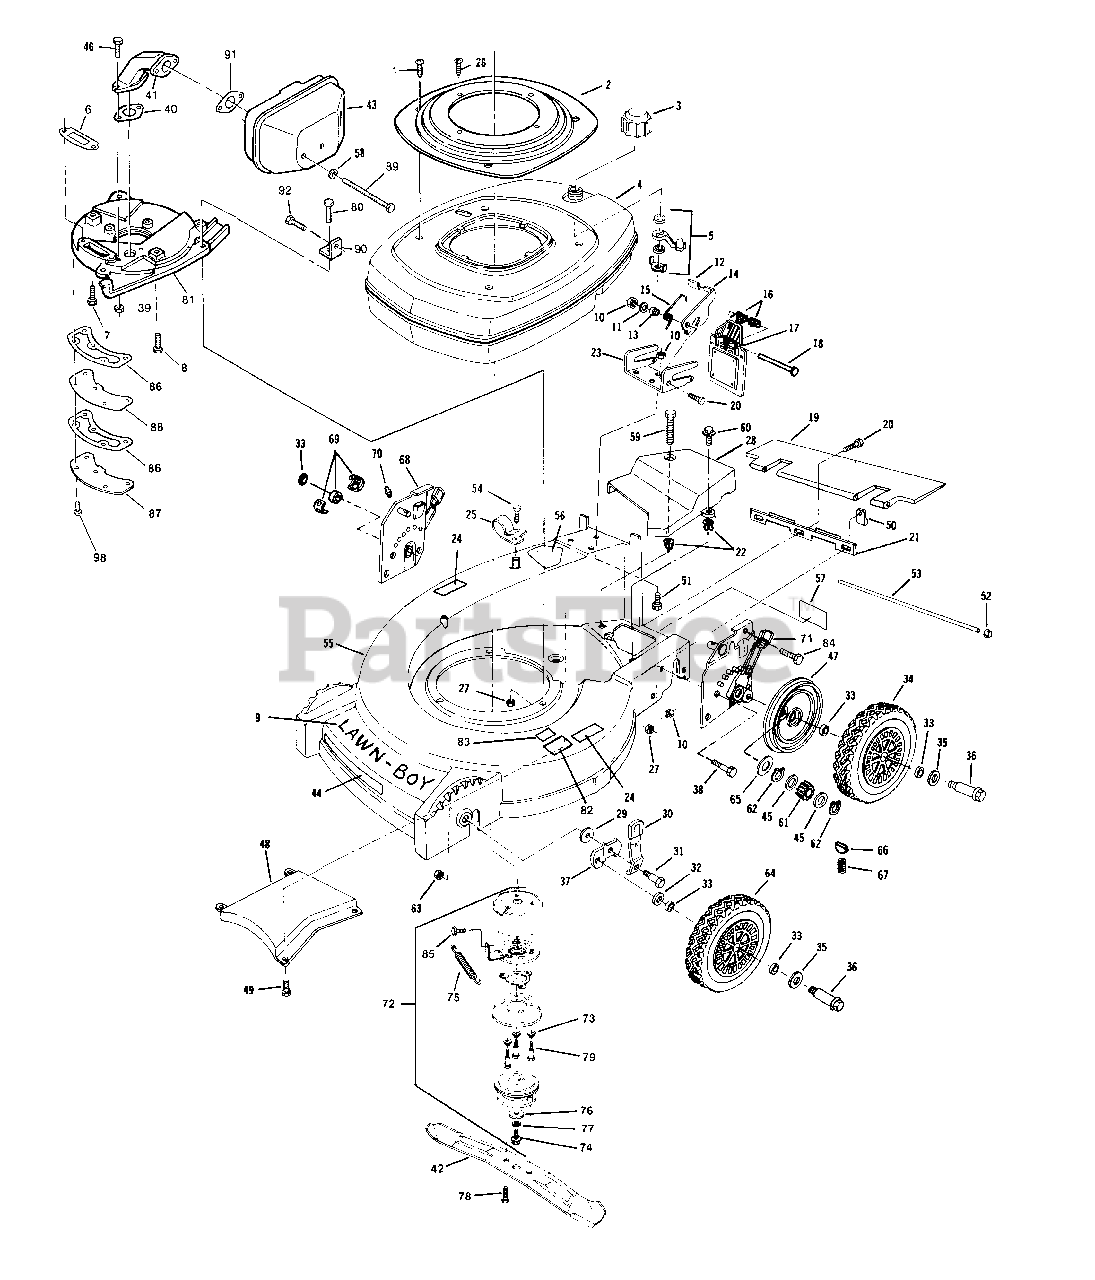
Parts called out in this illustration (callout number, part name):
1	Screw
2	Starter Base and Nut Assembly
3	Fuel Cap
4	Shroud Tank and Valve Assembly
5	Fuel Shut-Off Assembly
6	Gasket-Exhaust
7	Screw-Muffler to Block
8	Screw-Muffler Plate to Block
9	Decal-Lawn-Boy
10	Nut-Latch Brk't. and Trl. Shield
11	Washer
12	Knob-Latch
13	Stepped Spacer
14	Lever-Latch
15	Spring-Latch
16	Spring
17	Door
18	Rod
19	Shield-Trailing
20	Screw-Latch Bracket and Trailing Shield
21	Bracket-Bag Hanger
22	Grommet
23	Hinge Plate
24	Decal-Height Adjuster
25	Clamp-Cable and Primer Hose to Housing
26	Screw-Starter Mounting
27	Nut-Height Adjuster to Housing and Muffler Plate to Housing
28	Cover-Belt
29	Washer-Wheel Height Adjuster
30	Knob and Spring Assembly
31	Bolt-Shoulder
32	Washer
33	Washer-Felt
34	Wheel and Tire Assembly 8" SP
35	Washer-Wheel Bolt
36	Bolt-Shoulder Wheel
37	Bracket-Wheel Height Adjuster
38	Bolt-Height Adjuster Assembly
39	Nut
40	Gasket-Exhaust
41	Pipe-Exhaust
42	Blade 20"
43	Muffler
44	Decal-Headliner
45	Spacer
46	Screw
47	Cover-Wheel
48	Baffle
49	Screw
50	Clamp-Rod
51	Screw-Truss Head
52	Nut-Rod
53	Rod-Trailing Shield
54	Screw-Clamp to Housing
55	Housing-20" Assembly
56	Decal-Bld Contact Wrng.
57	Decal-Caution
58	Washer
59	Screw-Hex Head
60	Screw-Shoulder Idler
61	Pinion
62	Retaining Ring
63	Nut-Wheel Height Adjust
64	Wheel and Tire Assembly 8"
65	Washer
66	Key
67	Spring
68	Height Adjuster Asy.-R.H.
69	Bearing and Retainer Asy.
70	Fitting
71	Height Adjuster Asy.-L.H.
72	Clutch Assembly
73	Spring
74	Screw
75	Spring
76	Washer
77	Lockwasher
78	Screw
79	Screw
80	Bolt
81	Mounting Plate
82	Starting Pad
83	Decal
84	Bolt
85	Bolt-Cable to Arm
86	Gasket-Muffler
87	Cover Gasket
88	Baffle
89	Screw
90	Bracket-Muffler
91	Gasket-Muffler
92	Screw
